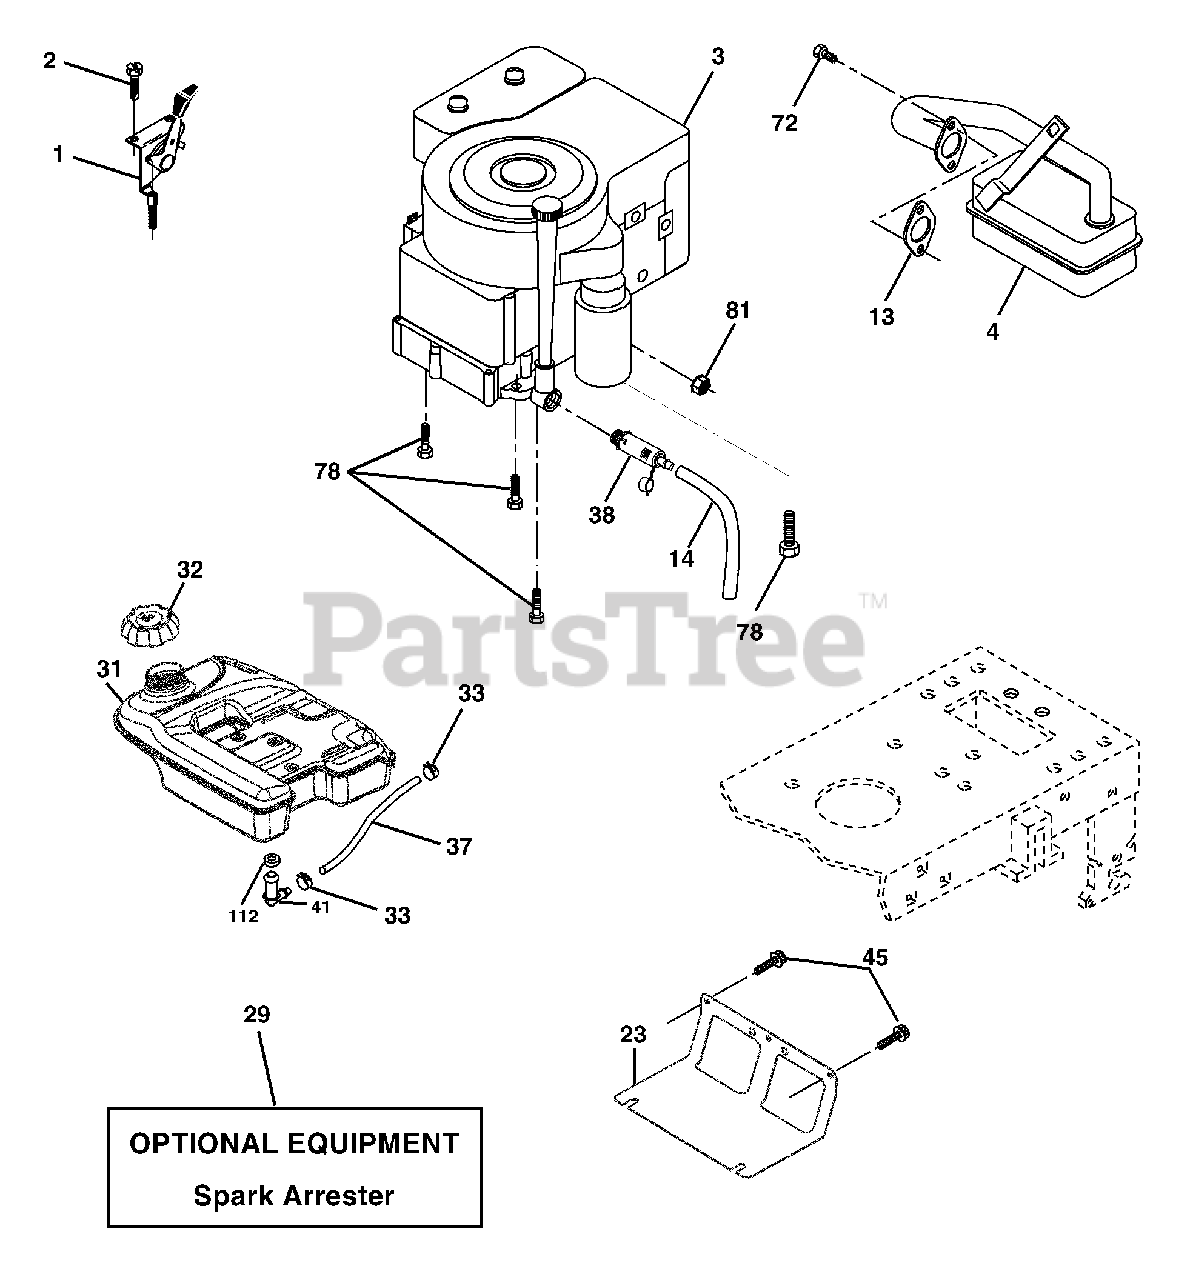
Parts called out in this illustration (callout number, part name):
1	Control Throttle
2	Screw Hwhd Hi-Lo #13-16 x 3/4
4	Muffler
13	Muffler Gasket
14	Tube Drain oil
23	Shield Heat
29	Kit Spark Arrestor (Flat Scrn)
31	Tank Fuel 4.0 Rear
32	Cap Asm Fuel
33	Clamp Hose Black
37	Line Fuel
38	Plug Drain Oil Easy
41	Stem Tank Fuel
45	Screw Hexwsh Thdr 3/8-16 x 3/4
72	Screw 5/16-18 x 1
78	Screw 3/8-16 x 1-1/4
81	Nut Keps Hex 1/4-20 unc
112	Bushing
